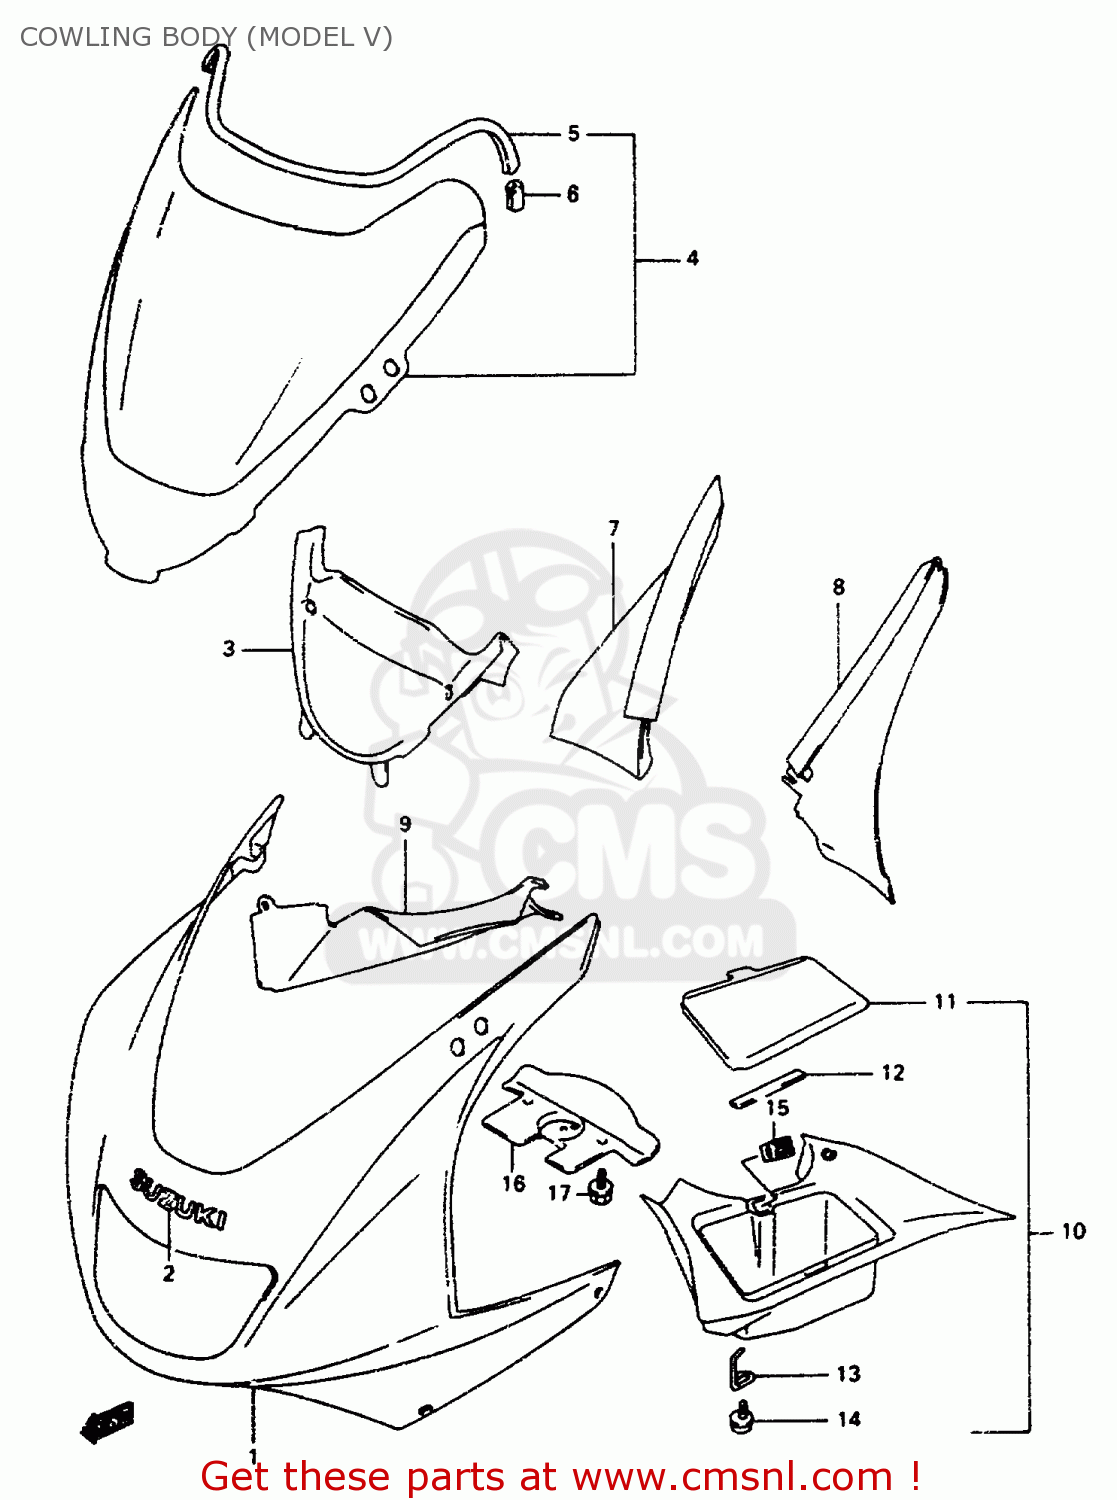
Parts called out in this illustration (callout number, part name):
1	COWLING ASSY,BODY (RED)
2	EMBLEM,SUZUKI(SILVER)
3	PANEL,COWLING CTR
4	WINDSCREEN SET
5	MOLDING WINDSCREEN
6	CLIP,WINDSCREEN MOLDING
7	PANEL,UPR,R
8	PANEL,UPR,L
9	PANEL,SIDE,R
10	PANEL ASSY,SIDE,L
11	LID,PANEL BOX
12	CUSHION,LID
13	HINGE,PANEL LID
14	SCREW
15	LOCK,I/P CTR BOX
16	COVER,COWLING FR LWR
17	BOLT(6X12)
